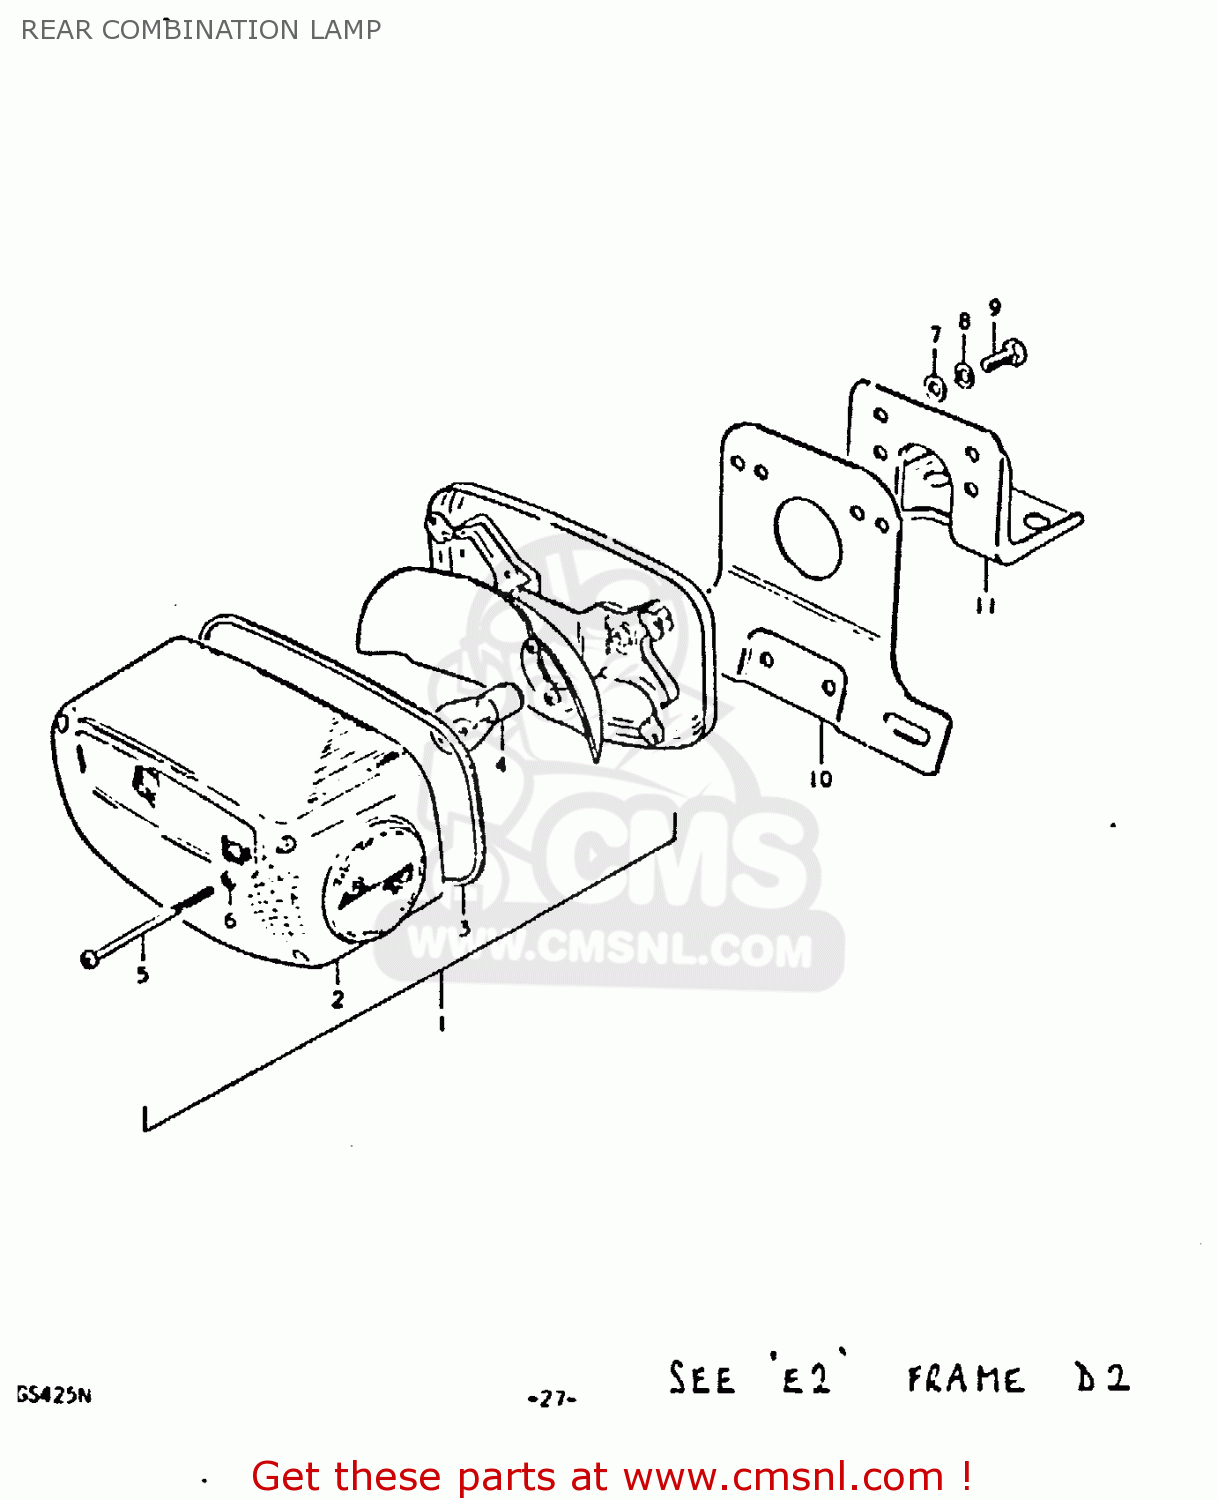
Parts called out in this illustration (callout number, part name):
1	LAMP ASSEMBLY,REAR COMBINATION
2	LENS,REAR COMBINATION LAMP
3	GASKET (NAS)
4	BULB(12V23W)
5	SCREW
6	GASKET (NAS)
7	WASHER
8	LOCK WASHER
9	BOLT
10	BRACKET,LICENSE PLATE
11	BRACKET,LICENSE PLATE
